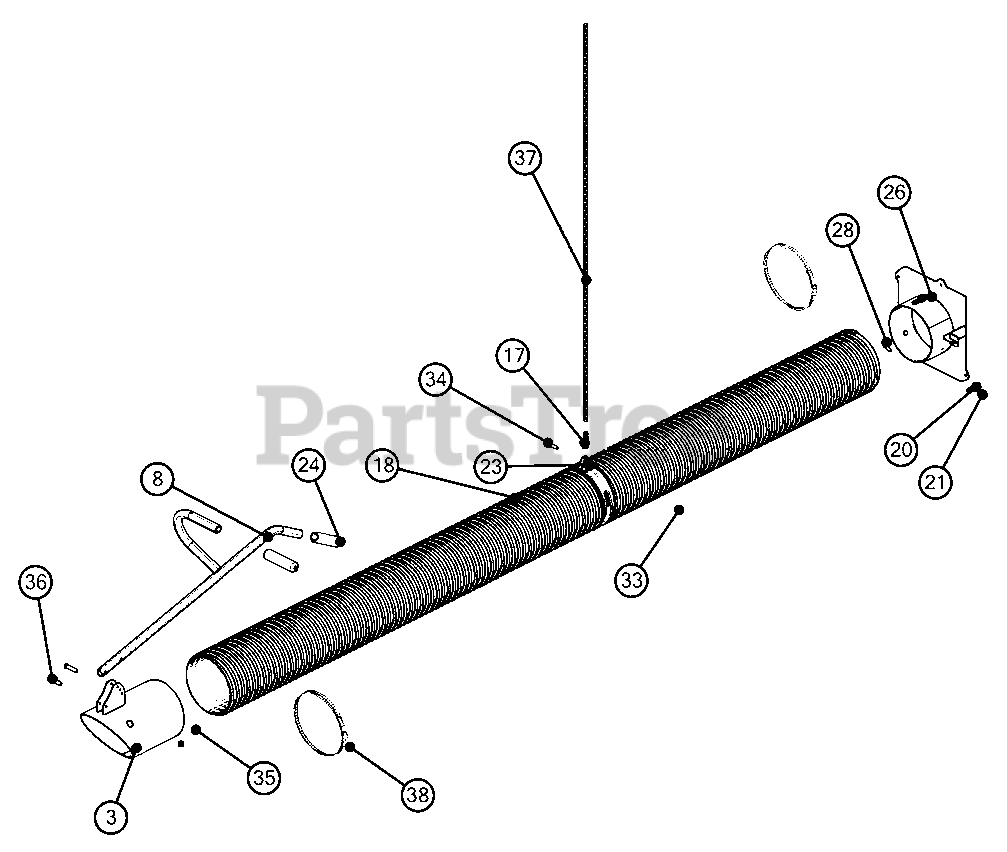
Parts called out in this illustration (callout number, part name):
3	WLDT, TUBE 8" PICKUP
8	WLDT, HANDLE TRUCK LOADER
17	HOOK SPRING 2450S-3/16"
18	HOSE 8" X 10' FLX-THANE CLEAR
20	CLIP, HOSE
21	NUT-LK-NYL-FLG .25-20 YWZC
23	CLAMP, 8"
24	HANDLE GRIP
26	WLDT, INTAKE ADAPTER 8"
28	WLT RDHDSQNK GR5 Y
33	NUT-LK-NYL-FLG .25-20 YWZC
34	BLT HEX .25-20 X 1.75 GR5 YWZC
35	NUT-LK-NYL-FLG .31-18 YWZC
36	BLT-HEX .31-18 X 1.75 GR5 YWZC
37	CHAIN, .148 X 5 FOOT
38	8" BRIDGE CLAMP
